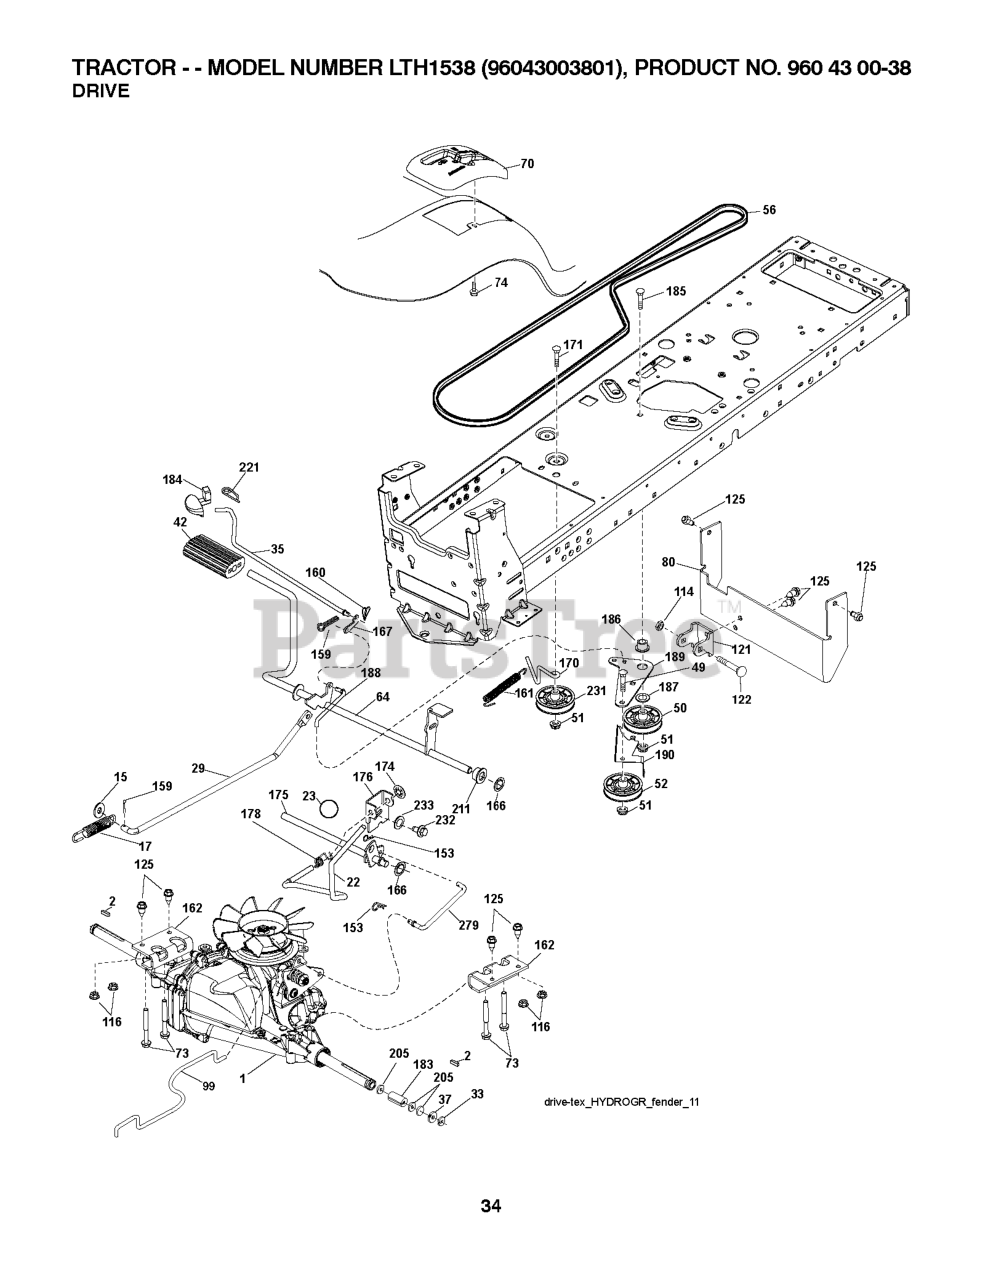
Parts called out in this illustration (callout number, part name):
2	SQUARE KEY
15	WASHER
17	SPRING.BRAKE.HG3000/3500
22	ROD.SHIFT.FENDER.TLT.2006
23	KNOB.DELUXE.(PISTOL.GRIP).BLAC
29	ROD.BRAKE.T2.TEX
35	ROD.CNTRL.PARK.PREDATOR.LT.TEX
42	PEDAL COVER T
50	IDLER.FLAT.910.OFFSET
51	NUT LOCK FLG 3/8-16 UNC
52	IDLER.V-GROOVE.910.OFFSET
64	SHAFT.ASM.PEDAL.BRAKE.
70	CONSOLE SHIFT
73	BOLT HEX 5/16-18 GR 5
74	SCREW.HI-LO.CONSOLE
80	RP.STRAP.TORQUE.FS.T2
99	ROD.ASM.BYPASS.SPRING.T2.FS
114	NUT.71038.31-18.HEX.NYLOCK
116	NUT LOCK HEX FLANGE 5/16-18
121	BRACKET STRAP TORQUE
122	BOLT.5/16-18X2.5
125	SCREW
153	RETAINER M
159	COTTER PIN
160	RETAINER CLIP
161	SPRING.RETURN.CLUTCH.2006
162	ADAPTER.TRANSAXLE.T2.TLT.DRWBR
165	BUSHING.SHAFT.BRAKE.HAND
166	NUT.PUSH.625.2006
167	LATCH.BRAKE.SPRING
170	KEEPER.V-IDLER.CENTER.
174	NUT.PUSH.500.2006
175	SHAFT.ASM.SHFT.T2.TLT
176	ARM.CLEVIS.ROD.SHIFT
178	SPRING.SHIFT.GT2006
183	SPACER, AXLE PVST
184	HANDLE PARKING BRAKE
186	SPACER.RETAINER
187	WASHER 12/32X2X10GA
188	RP.LINK.CLUTCH.GROUND.DRIVE
189	BELLCRANK.GROUND.DRIVE.TEX.
190	KEEPER.BELLCRANK.DRIVE
221	RETAINER.SPRING.CLIP.H
231	IDLER.V-GROOVE.1.688.OFFSET
232	BOLT FIN HEX 7/16-14 X 1
233	WASHER SERRATED
279	LINK SHIFT
